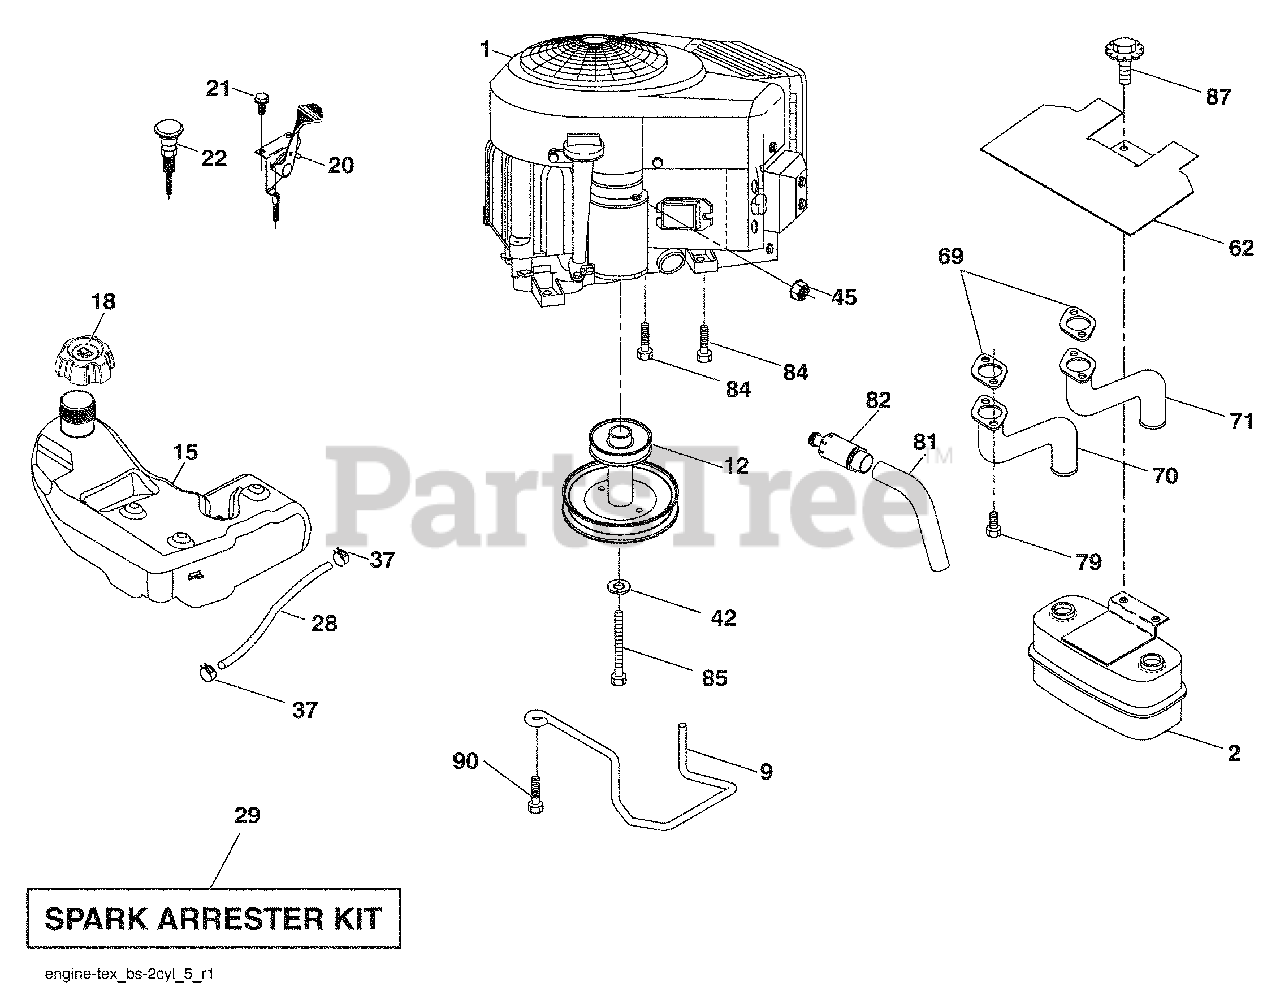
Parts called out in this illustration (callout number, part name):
9	Keeper Belt Engine
12	Pulley Engine
15	Tank Fuel
18	Cap Asm
20	Control Throttle
21	Screw #10 x 0.750 BOS Thread
22	Control Choke
28	Fuel Line
29	Spark Arrester Kit
37	Clamp Hose
42	Washer Lock 7/16
45	Nut Keps Hex 1/4-20 unc
62	Shield Heat Muffler
70	Tube Exhaust LH
71	Tube Exhaust RH
79	Screw Socket Head 5/16-18 x 1
81	Tube Drain Oil Easy
82	Plug Drain Oil
84	Screw 3/8-16 x 1-1/4
85	Bolt Hex 7/16-20 x 4 Gr. 5
87	Bolt 5/16-18 unc x 1 w/Sems
90	Screw 3/8-16 x 1
